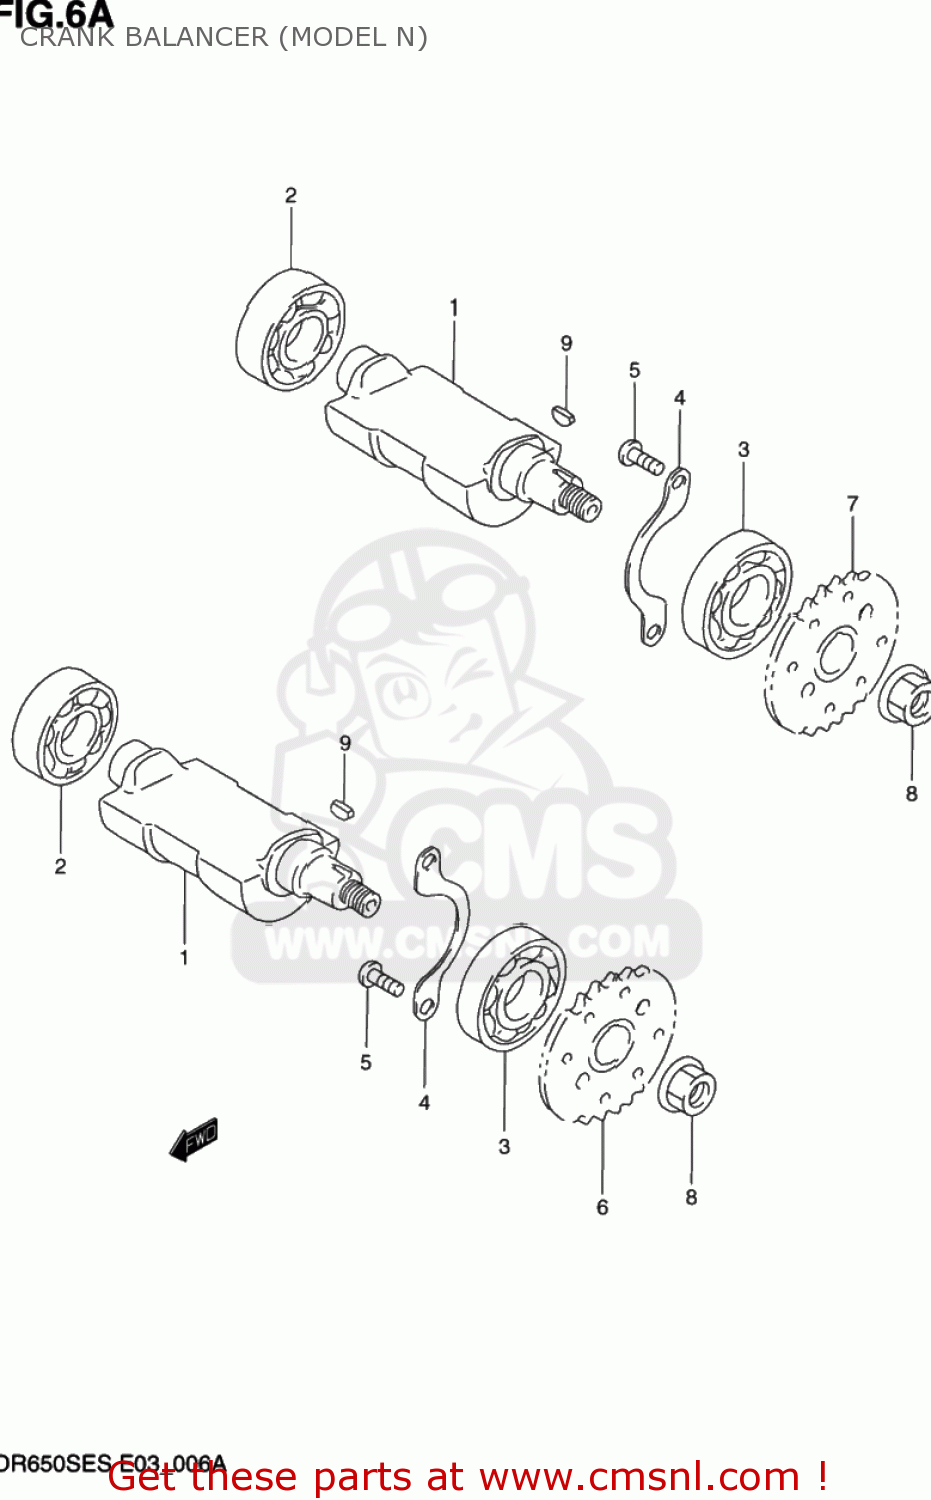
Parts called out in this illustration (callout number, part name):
1	BALANCER,CRANKSHAFT
2	BEARING(20X42X12)
3	BEARING(20X47X12)
4	RETAINER,CRANK BAL BEARING
5	SCREW
6	SPROCKET,BALANCER DRIVE
7	SPROCKET,BALANCER DRIVEN RR
8	NUT
9	KEY
